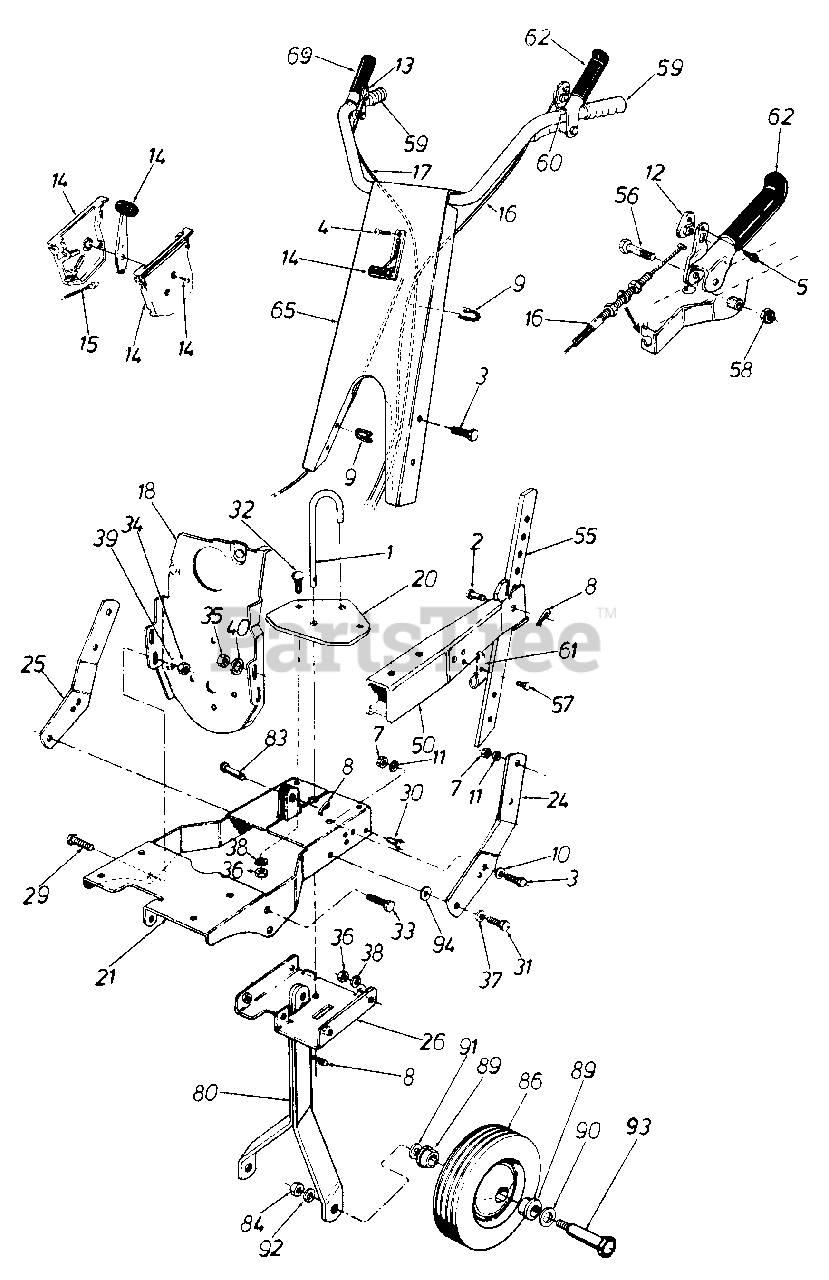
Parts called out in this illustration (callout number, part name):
1	U-Clevis Pin .5" Dia.
2	Clevis Pin 2" Lg.
3	Hex Bolt 3/8-16 x 1.0" Lg.
4	Truss Mach. AB-Tap Scr. #10 x .5" Lg.
5	Hex B-Tap Scr. #10 x .44" Lg.
7	Hex Nut 3/8-16 Thd.
8	Internal Coter Pin
9	Cable Tie
10	Bell-Wash. 3/8" I.D.
11	L-Wash. 3/8" I.D.
12	Barrel Cable Hold-Down-L.H.
13	Barrel Cable Hold-Down-R.H.
14	Throttle Control Box Ass'y.
15	Throttle Control Wire-35"
16	Clutch Control Cable-
17	Clutch Control Cable-
18	Mounting Plate Ass'y.
20	U-Channel Plate
21	Tiller Frame Ass'y.
24	Handle Brkt.L.H.
25	Handle Brkt.R.H.
26	U-Channel Brkt. Ass'y.
29	Hex Bolt 3/8-24 x 1.0"
30	Hex Sems Scr. 5/16-18 x .75 Lg.
31	Hex Bolt 3/8-16 x 1.0" Lg.
32	Carr. Bolt 5/16-18 x .75 Lg.
33	Hex Bolt 1/2-20 x 1.0" Lg.
34	Hex L-Nut 3/8-24 Thd.
35	Hex L-Nut 1/2-20 Thd.
36	Hex Nut 5/16-18 Thd.
37	Bell-Wash. 3/8" I.D.
38	L-Wash. 5/16" I.D.
39	Extern. L-Wash. 3/8" I.D.
40	Extern. L-Wash. 1/2" I.D.
50	Tailpiece Ass'y.
55	Depth Stake
56	Hex Bolt 3/8-24 x 2.0" Lg.
57	Hex TT-Tap Scr. 1/4-20 x 1/2" Lg.
58	Hex Ins. L-Nut 3/8-24 Thd.
59	Grip Handle
60	Push Cap
61	Depth Stake-Spring
62	Clutch Grip Ass'y.L.H.
65	Handle Ass'y.
69	Clutch Grip Ass'y.R.H.
80	Wheel Yoke Ass'y.
83	Clevis Pin 2" Lg.
84	Hex Jam Nut 1/2-20 Thd.
86	Wheel Ass'y. 10 x 1.75
89	Flange Brg. .631 I.D.
90	Fl-Wash. .640" x 1.24" x .06"
91	Bell-Wash. 1/2" I.D.
92	L-Wash. 1/2" I.D.
93	Shoulder Bolt .625" Dia. x 2.75"
94	Fl-Wash. 3/8" I.D.
